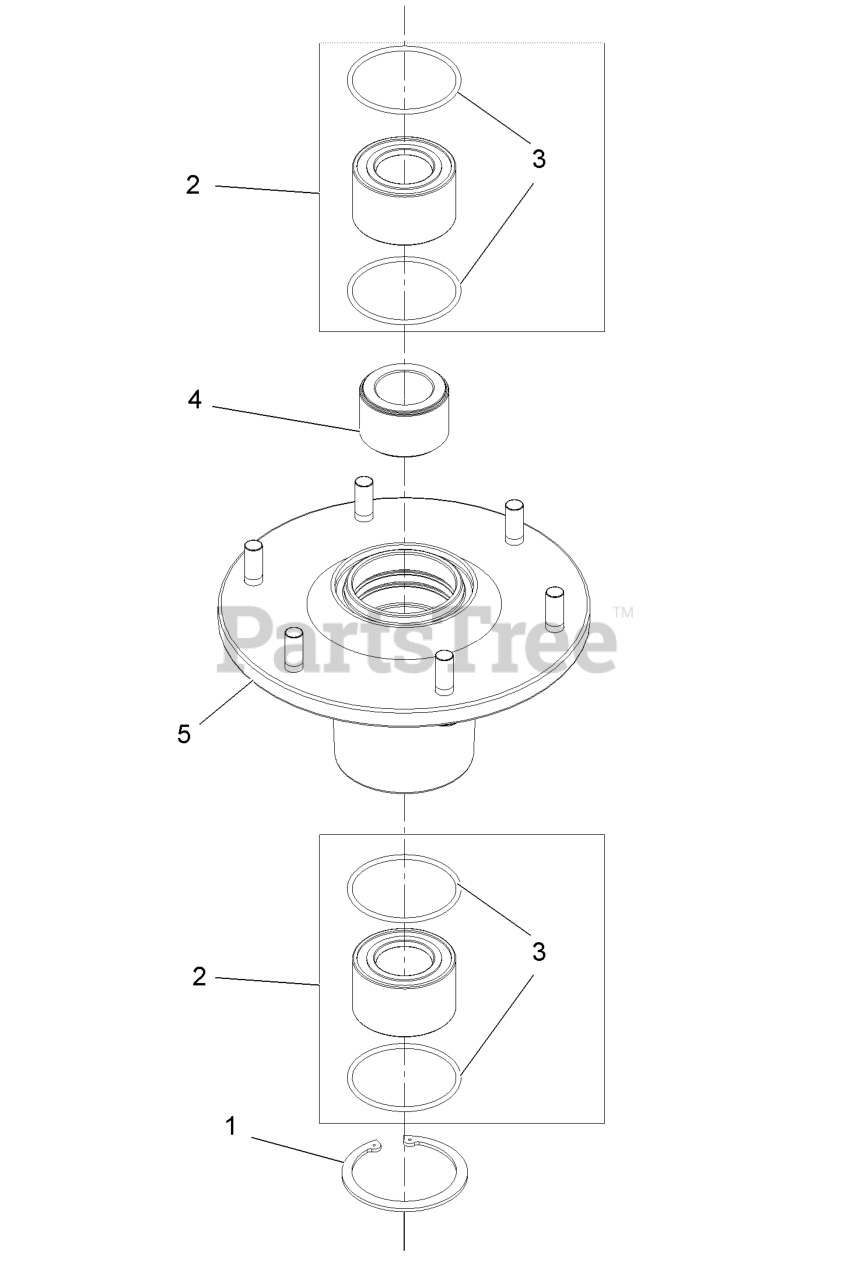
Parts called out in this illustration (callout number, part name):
1	Ring-Retaining
2	Asm, Bearing W/O-Rings
4	Spacer, Bearing
5	Asm, Housing W/Studs
